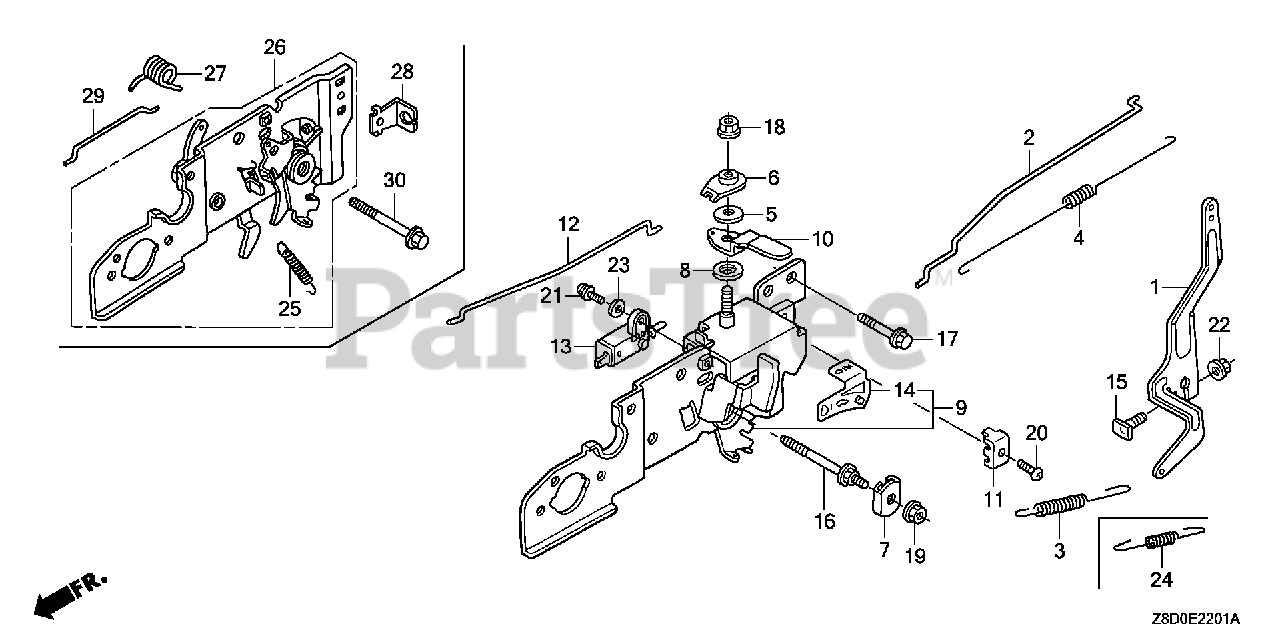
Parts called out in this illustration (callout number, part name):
1	ARM, GOVERNOR
2	ROD, GOVERNOR
4	SPRING, THROTTLE RETURN
13	SWITCH ASSY., ENGINE STOP (N.O)
15	BOLT, GOVERNOR ARM
20	SCREW, PAN (5X8)
21	SCREW-WASHER (4X12)
22	NUT, FLANGE (6MM)
23	WASHER, PLAIN (4MM)
24	SPRING, GOVERNOR
25	SPRING, LEVER
26	BASE, CONTROL
27	SPRING, CONTROL LEVER RETURN
28	HOLDER, CABLE
29	ROD, CHOKE
30	BOLT, FLANGE (6X50)
